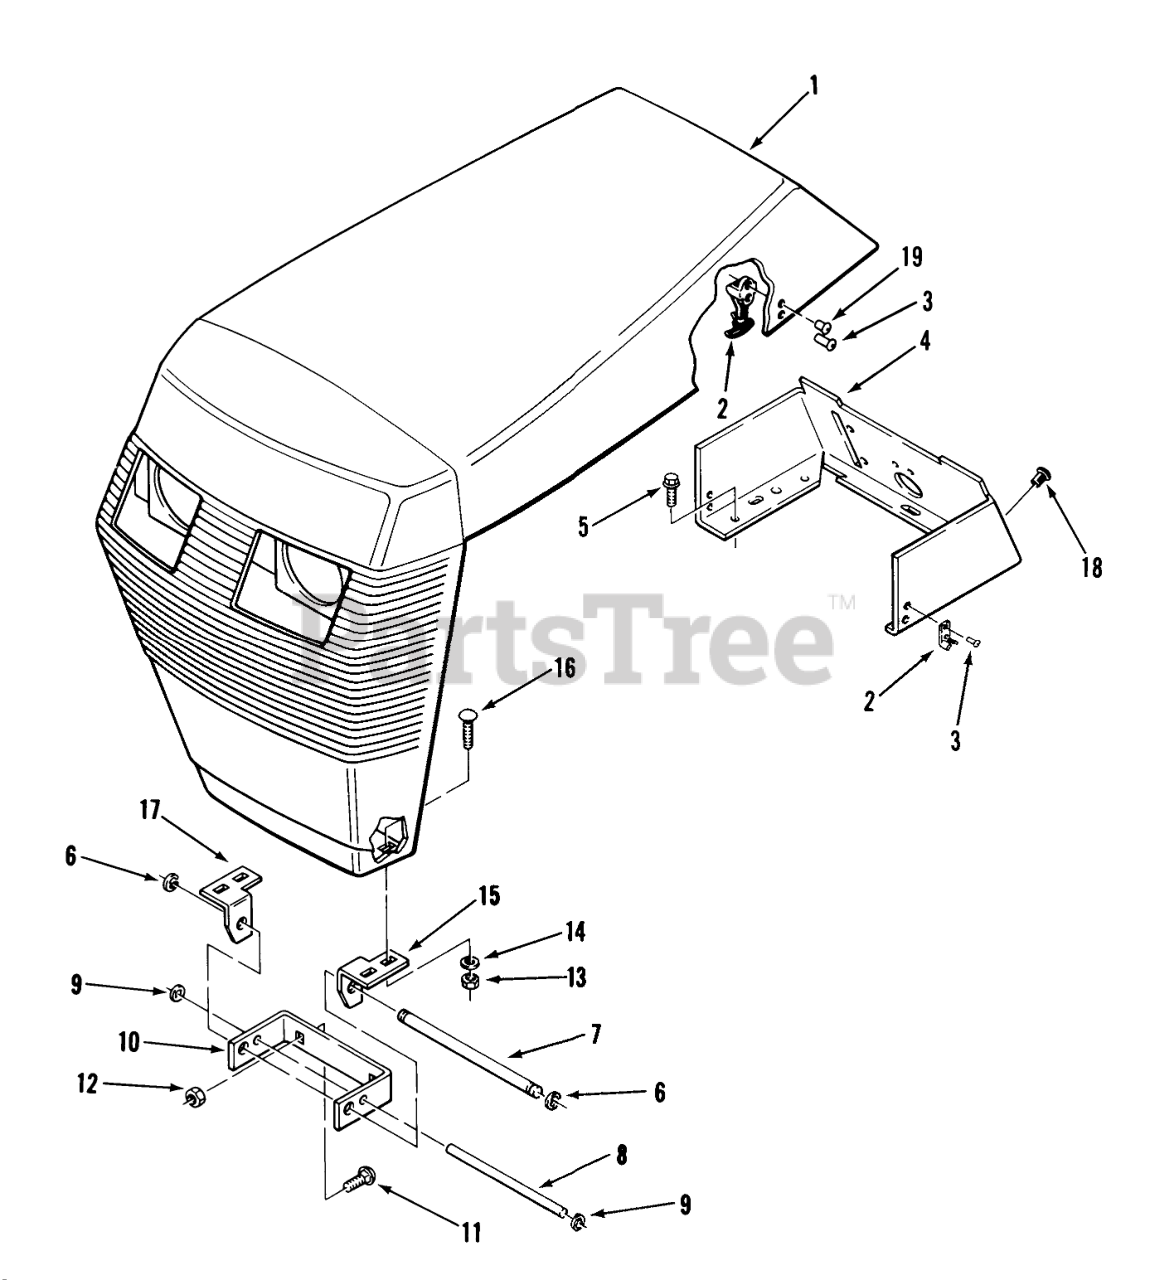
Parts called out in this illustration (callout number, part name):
1	Hood LT-1100 Only
1	Hood LT-1600 Only
2	ASSY-FLEX DRAW LATCH
3	RIVET -4
4	Console
5	SCREW
6	RING-RETAINING
7	ROD-GRILL PIVOT
8	ROD-HOOD STOP
9	SPEED NUT
10	Bracket Hood Pivot
11	Bolt-Carriage
12	Nut
13	Nut
15	BRKT-GRILL PIVOT R (NS)
16	Bolt-Carriage
17	BRKT-GRILL PIVOT R
18	NYLON PLUG
19	RIVET
